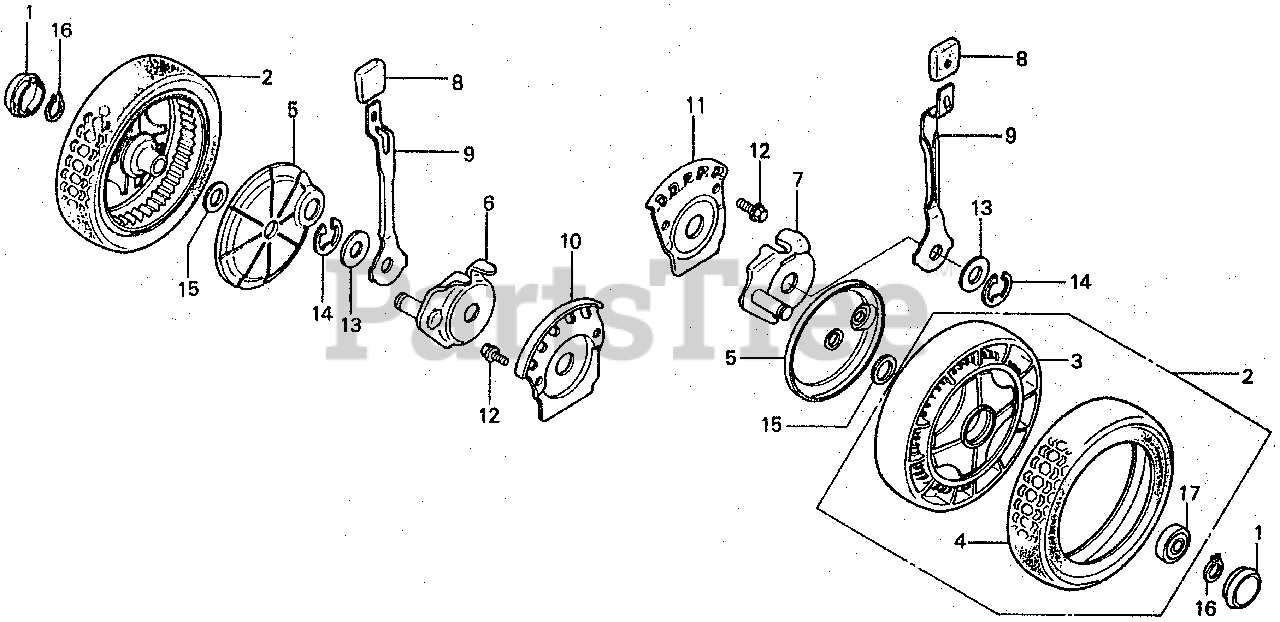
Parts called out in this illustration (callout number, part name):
1	CAP, WHEEL
2	WHEEL ASSY., RR. *NH31* (MCKINLEY WHITE)
3	HUB, RR. WHEEL *NH31* (MCKINLEY WHITE)
3	HUB, RR. WHEEL *NH31* (MCKINLEY WHITE) (NOT AVAILABLE)
4	TIRE, RR. (8INCH)
5	COVER, WHEEL
6	ADJUSTER KIT, R. RR. HEIGHT
7	ARM, L. RR. ADJUSTING
8	GRIP, ADJUSTER
9	PLATE, RR. ADJUSTING
10	PANEL, R. RR. ADJUSTING
11	PANEL, L. RR. ADJUSTING
12	BOLT, FLANGE (6X12) (CT200)
13	WASHER, PLAIN (22MM)
14	E-RING (19MM)
15	WASHER, THRUST (15MM)
16	CIRCLIP (OUTER) (15MM)
17	BEARING, RADIAL BALL (6202)
